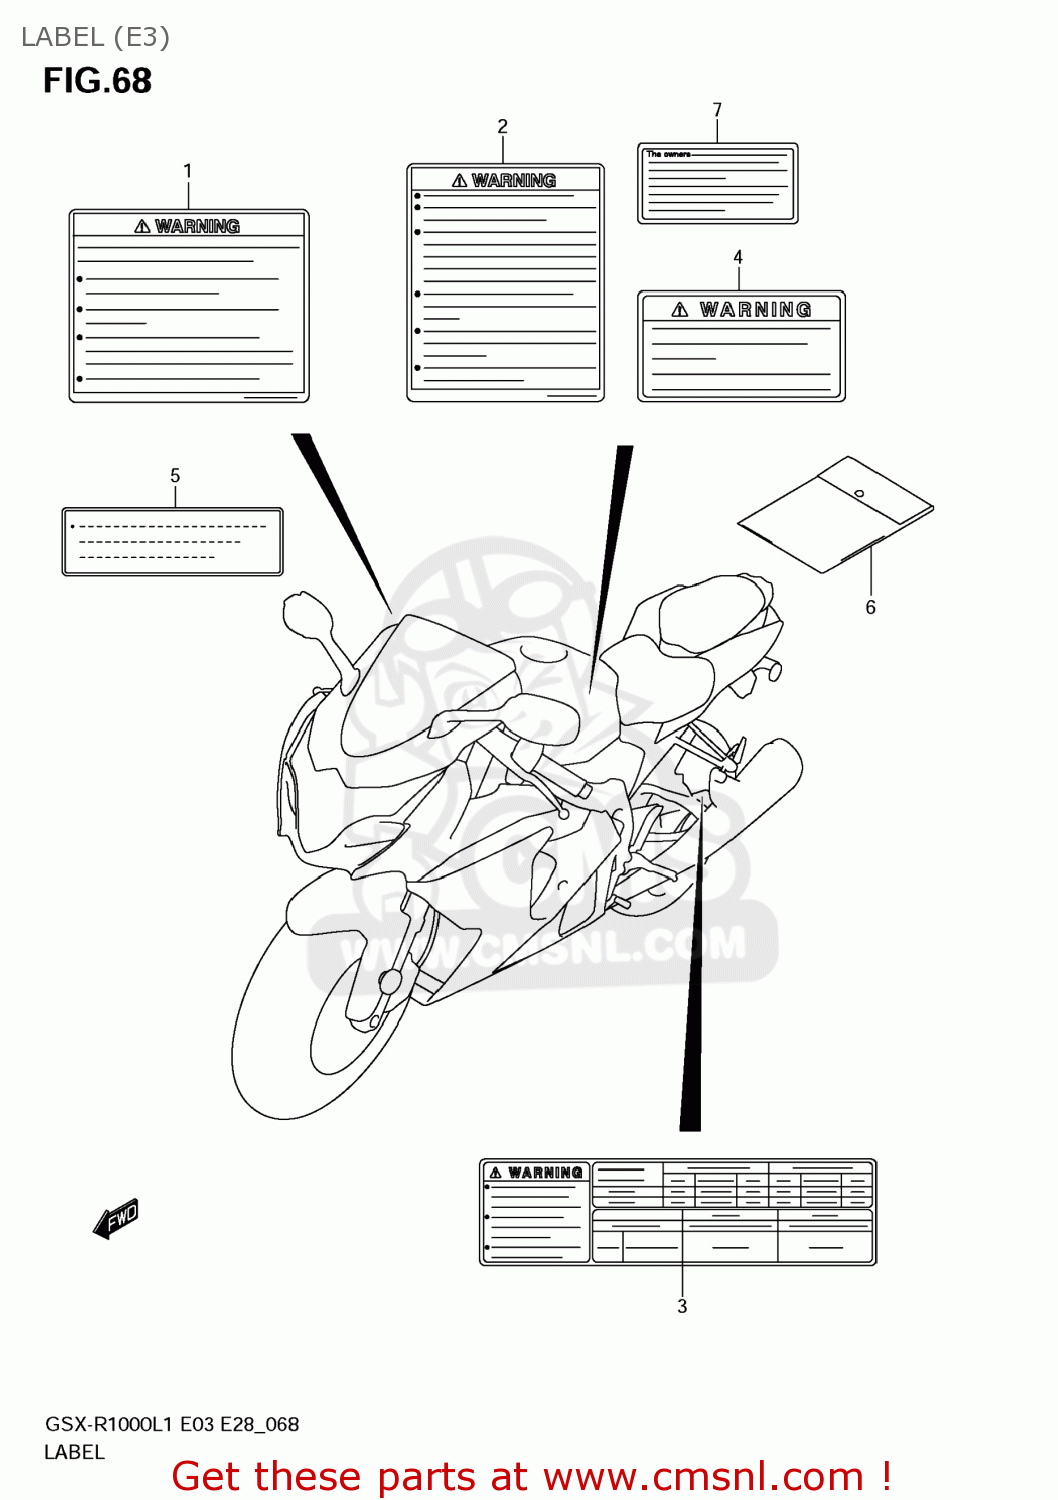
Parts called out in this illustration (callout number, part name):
1	LABEL,GENERAL WARNING
2	LABEL,SCREEN
3	LABEL,TIRE INFORMATION
4	LABEL,WARNING STEERING
5	LABEL,FUEL INFORMATION
6	BAG COMP,OWNERS MANUAL
7	LABEL,MANUAL NOTICE
8	MANUAL,OWNER'S
